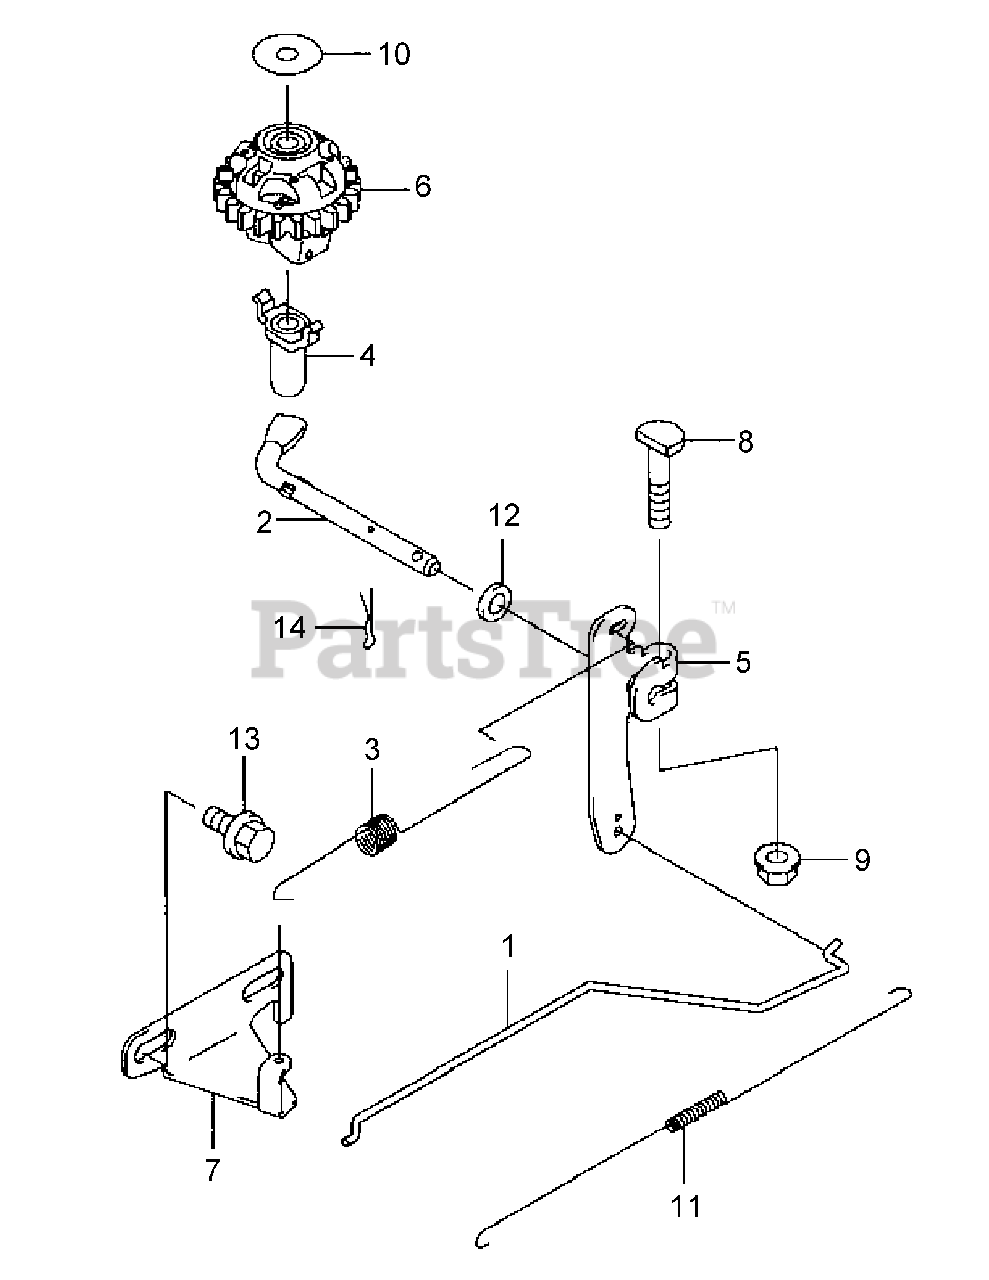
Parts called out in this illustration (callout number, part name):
1	Throttle Link
3	Governor Spring
4	Sleeve
6	Governor Assy.
7	Control Panel
9	Nut
11	Throttle Spring
12	Washer, 6.5x11.5x2.0
13	Flanged Bolt
